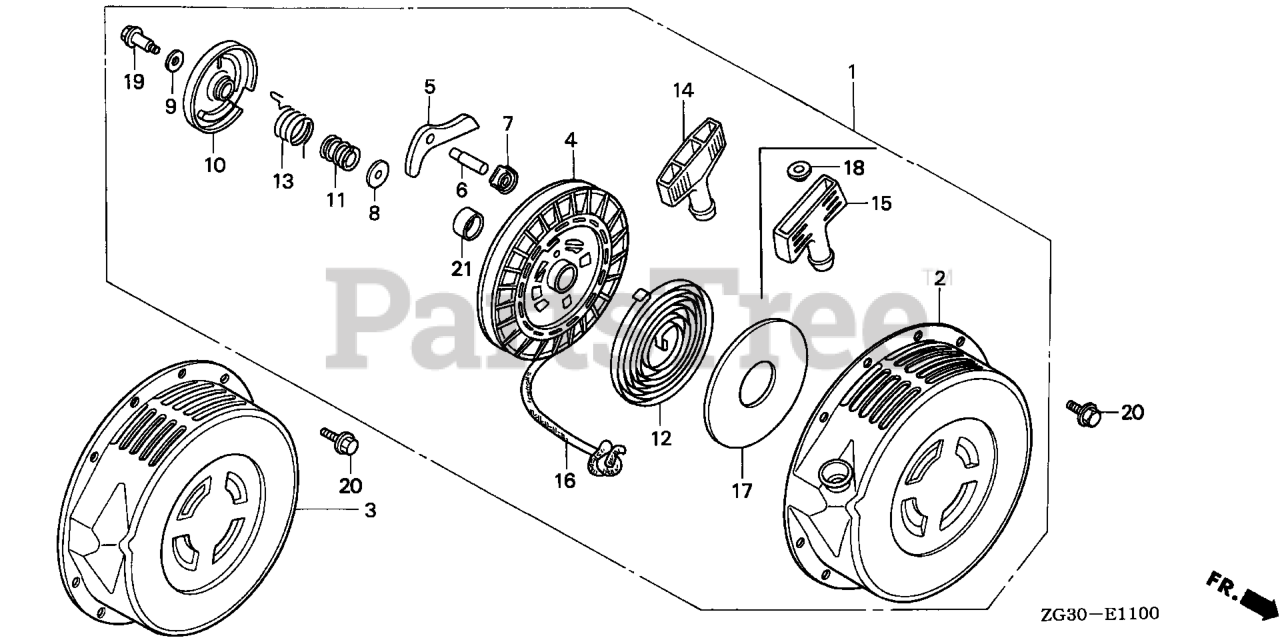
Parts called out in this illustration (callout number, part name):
1	STARTER ASSY., RECOIL *NH116M* (URBAN SILVER METALLIC)
2	CASE, STARTER
4	REEL, STARTER
5	RATCHET, STARTER
6	SHAFT, RATCHET
7	PLATE, GUIDE
8	PLATE A, FRICTION
9	PLATE B, FRICTION
10	COVER, REEL STARTER
11	SPRING, FRICTION
12	SPRING, RETURN
13	SPRING, TORSION
14	GRIP, STARTER
15	GRIP, STARTER
16	ROPE, STARTER (#6X64")
16	ROPE, STARTER
18	GRIP, REINFORCEMENT
19	BOLT, REEL COVER
19	BOLT (6MM)
20	BOLT, FLANGE (6X8)
21	COLLAR
